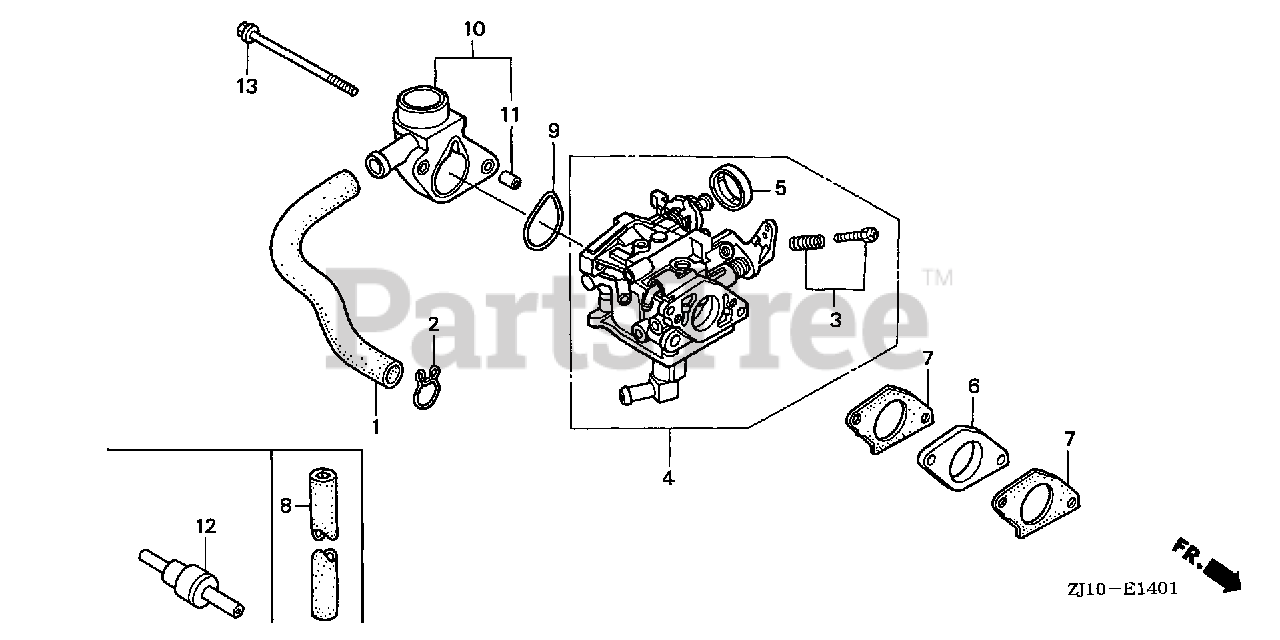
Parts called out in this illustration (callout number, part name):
1	TUBE, BREATHER
2	CLIP, BREATHER TUBE
4	CARBURETOR ASSY. (BGL1A A)
5	CAP, CHOKE DUST
6	INSULATOR, CARBURETOR
7	GASKET, CARBURETOR
8	RUBBER, SUPPORTER
9	GASKET, AIR CLEANER
10	ELBOW, AIR CLEANER
11	COLLAR, DISTANCE
12	VALVE, DASHPOT CHECK
13	BOLT, FLANGE (6X105)
